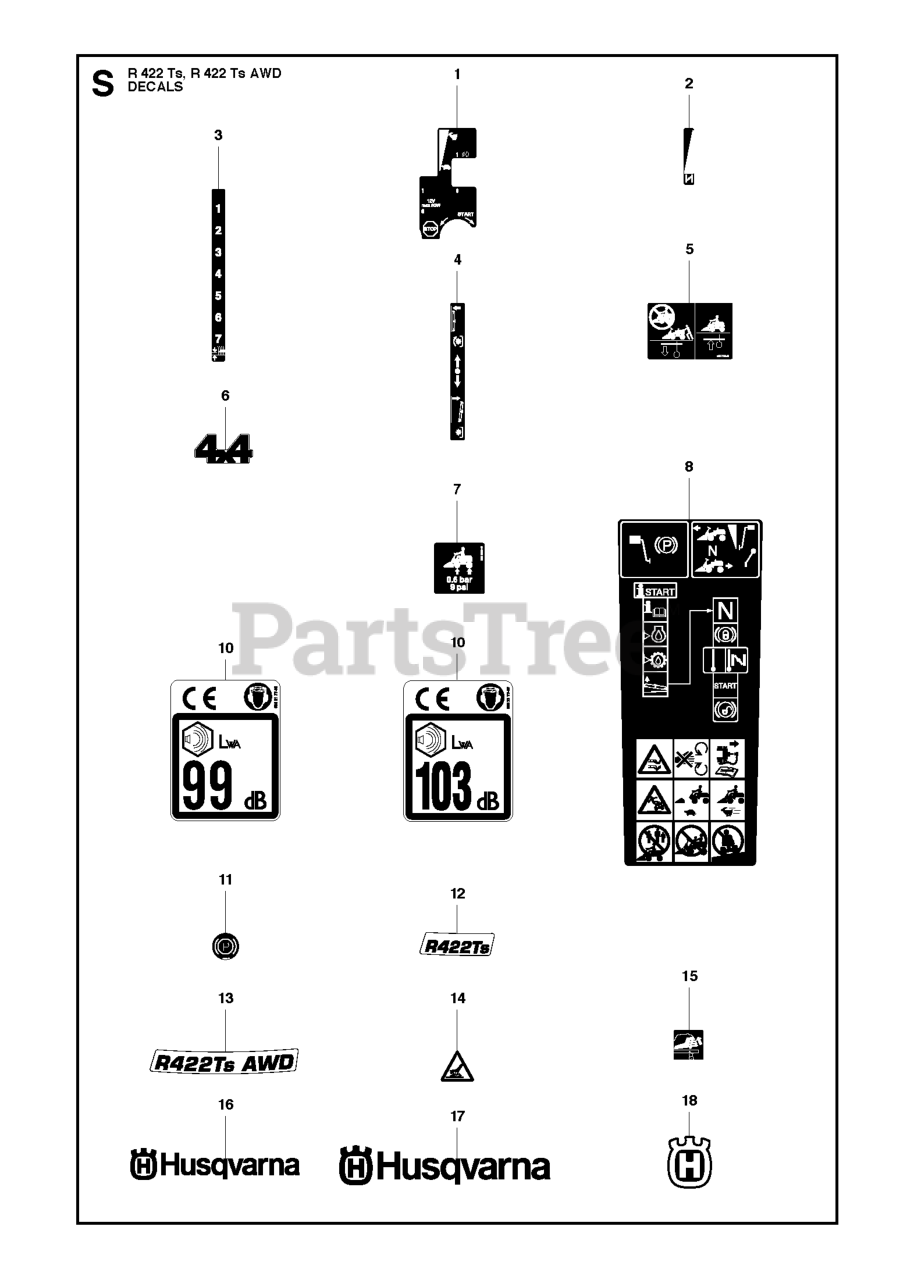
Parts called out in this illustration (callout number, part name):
5	DECAL
6	LABEL
8	Decal - Warning
11	Decal
